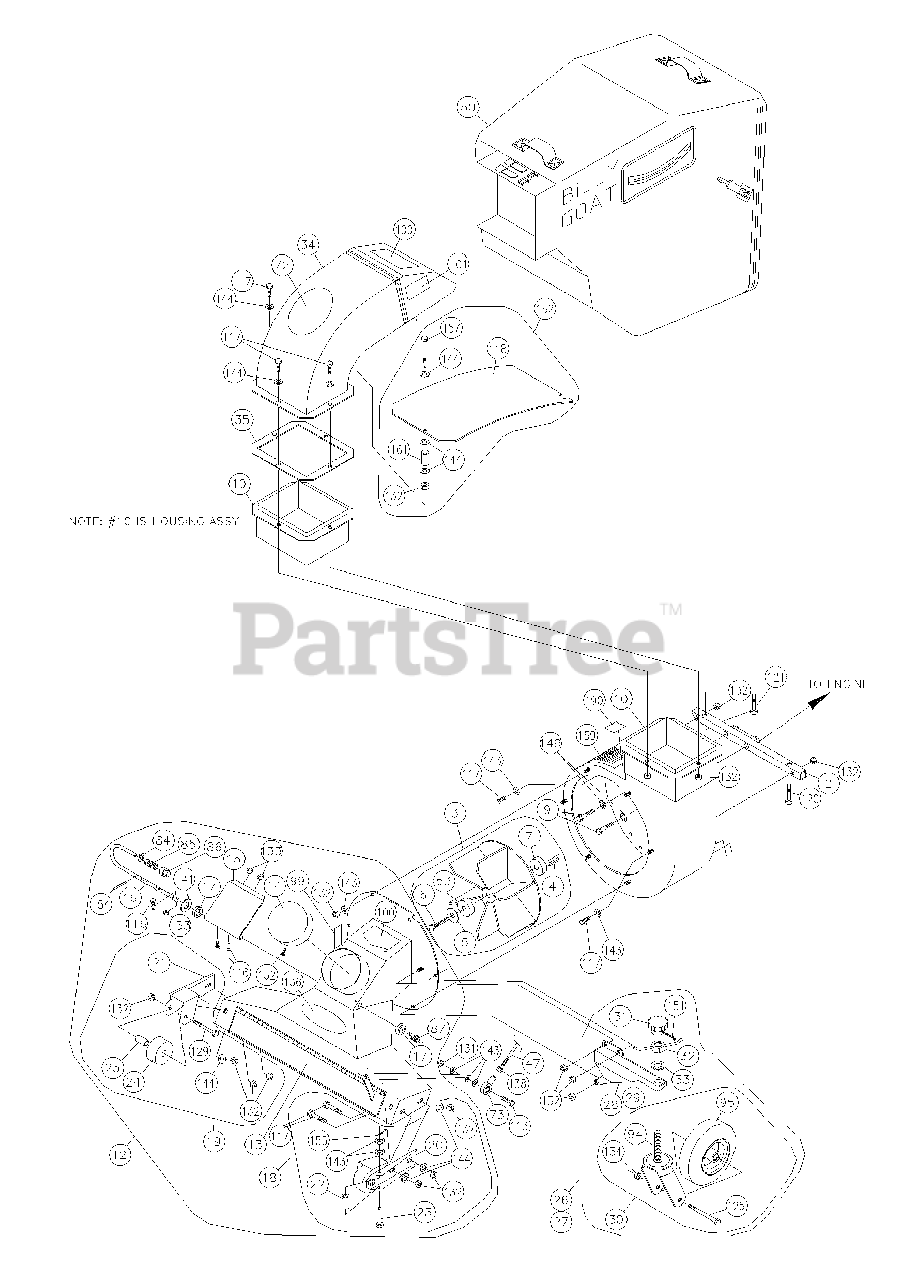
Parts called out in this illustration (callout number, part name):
1	ENGINE 9 HP HONDA
2	ANGLE MOUNT HDLE WA
3	IMPELLER ASSY VQ (INCLUDES ITEM 4,5,6,7)
4	KEY 0.25 SQ. X 2.75"
5	WASHER LOCK 7/16 S/T MED
6	SCREW CAP 7/16 NF x 2 1/4 GR8 TORQ 55-60 FT LBS (75-81 N.m)
7	SPACER ENGINE
8	WASHER LOCK 5/16 S/T MED
9	SCREW CAP 5/16 NF x 2 1/2 GRD. 8
10	HOUSING ASSEMBLY W/LABELS VQ
11	FRAME WA VQ
12	NOZZLE ASSEMBLY VQ
13	NOZZLE ASSY W/LABELS
14	HOSE TUBE PLUG VQ
15	PLATE DOOR NOZZLE HOSE
16	ROD DIVERTER VQ
17	GROMMET FLG. 1/2 MOLDED
18	BRKT BOGIE ASSY LH
19	BRKT BOGIE ASSY RH
20	BRKT BOGIE WA LH
21	BRKT BOGIE WA RH
22	ROLLER GUIDE
23	PIN ROLLER
24	WHEEL BOGIE 3"
25	SPACER 5/16 X 1 5/8
26	CASTER & BRKT LH ASSY SEMI-PNEU VQ
27	CASTER & BRKT RH ASSY SEMI-PNEUVQ
28	BRKT LH WA 8" CASTER
29	BRKT RH WA 8" CASTER
30	CASTER ASSY 8" SEMI-PNEU 3/4 NC (INCL ITEM 33 (4), 94, 95, 125, 134)
31	KNOB HAND
32	NUT WING WA
33	WASHER 3/4 NYLON
34	ELBOW ASSY W/LABELS VQ
35	GASKET FLANGE TRANSITION VQ
36	HANDLE BRACE REAR
37	HANDLE LOWER VQ
38	TUBE HANDLE BAG SUPPORT
39	ROD BAG LOOP
40	PLUG TUBE INSERT 1" OD
41	HANDLE ASSY UPPER W/GRIP (39, 45, 46, 81, 114, 115, 131, 163)
42	SWITCH & WIRE ASSY(ITEMS 107,109,110)
43	CONTROL THROTTLE ASSY VQ SERVICE
45	DOOR NOZZLE FRICTION ASSY
47	ROD DOOR NOZZLE
48	BAR LEVER DOOR
49	PLATE FRICTION LIFT
50	BAG ASSY VQ / TURF BAG 830313
51	DIFFERENTIAL ASSY
52	SPROCKET 35 TOOTH #41
53	WASHER 1.5 OD X .453 ID X .25 THK
54	WHEEL 13" x 6.5" PNEU. SP
55	BRG ASSY VQSP
56	BRKT MOUNT BEARING
57	TRANSMISSION 5 SPEED 1 REV W/BRAKE (TECUMSEH)
58	CHAIN #41 x 68P VQSP
59	BELT “V” 4L x 34" OUTSIDE LG.
60	PULLEY 5.0 DIA. A SEC 0.625 ID
61	KEY HIPRO 3/16 X 3/4
62	PULLEY IDLER
63	BOLT IDLER
64	ARM IDLER WA VQ
66	BRKT TRANSMISSION WA VQ
67	BRKT TRANSMISSION REAR WELD LONG
68	BAR LINK SHIFT OFFSET VQ
69	GUARD DIFFERENTIAL VQ WELD
70	GUARD CHAIN VQ WELD
71	GUARD PULLEY W/LABEL
72	LABEL PRODUCT DECAL LG CIRCLE
73	SPHERICAL ROD END MSF-5
74	CABLE CLUTCH ASSY
75	CONTROL SHIFT VQSP
77	CONTROL ASSY VQSP
78	BRACKET CONTROL SHIFT
79	COVER CONTROL SHIFT VQ
80	ROD BAIL CLUTCH
81	GRIP HANDLE 1" x 13"
82	BAR BRAKE CABLE MOUNT
83	WIRE BELT GUIDE VQ
84	GRIP RING
85	SPRING COMPRESSION
87	SPRING DOOR
89	LABEL DANGER GUARDS
91	KEY SQ 3/16 X 1 3/4
92	WASHER 5/16 TWISTED TOOTH
94	FORK CASTER 8" 3/4 NC
95	VQ CASTER WHEEL
97	GUARD BRAKE VQ
98	GUARD BELT VQ
99	LABEL DIVERTER INSTRUCTIONS
100	LABEL DANGER
101	LABEL DANGER FLYING MATERIAL
103	PIN CLEVIS
106	LABEL CLUTCH VQ
107	SWITCH ROCKER
109	HARNESS ENGINE KILL 33"
110	CONNECTOR TAP
111	LABEL OIL
113	SCREW CAP 1/4-20 x 1 1/4"
114	RING RETAINING "E" 3/4
115	SCREW CAP 1/4-20 x 2"
116	SCREW CAP MACH 10-18X3/4 WF ZP
117	SCREW CAP 5/16-18 x 3/4"
118	PLATE DEBRIS DEFLECTOR
119	SCREW CAP 5/16-18 x 1 1/4"
120	SCREW CAP 5/16-18 x 1 1/2
121	SCREW CAP 5/16-18 x 1 3/4"
122	SCREWCAP 5/16-18 X 2 1/4"
123	BOLT CARRIAGE 5/16-18 X 3/4
124	SCREW #10-24NC X 5/8 HEX
125	SCREW CAP 1/2-10 x 4 1/2"
126	SCREW CAP 1/4 NF x 1/2 GR. 5"
127	SCREW CAP 5/16 NF x 1 3/4"
129	SCREWCAP 5/16-18 X 2 1/4"
131	NUT LOCK 1/4 NC
132	NUT LOCK 5/16 NC
133	NUT LOCK 10-24
134	NUT LOCK 1/2"-13 LT WT TH ZP
135	NUT LOCK 3/8 NC THIN HT
136	LABEL PRODUCT DECAL VQ
137	NUT REG. 3/8 NC
138	NUT REG. 5/16 NF
139	WASHER SAE 1/4
140	WASHER SAE 5/16
141	WASHER SAE 3/8
144	WASHER FLAT CUT 5/16
146	WASHER 3/4 (0.765 x 1.25 x 0.06)
147	BOLT SHOULDER 3/8 X 3/4"
148	WASHER LOCK 1/4
149	WASHER LOCK 5/16
150	LABEL SPEED CONTROL
151	SCREW MACH #10-24 x 2"
152	SCREW SHT. MTL 1/4 AB x 3/4
153	SCREW SELF-TAP 5/16 NC x 3/4 HEX
154	PIN ROLL 1/8 x 3/4
155	PIN COTTER 3/32 x 3/4
156	PIN COTTER 1/8 x 1"
157	SCREW CAP 5/16-18 x 2 3/4
158	LOOSE PARTS BAG ASSY VQ
159	LABEL DANGER INSTRUCTIONS
162	DEFLECTOR DEBRIS ASSY
163	SCREW CAP 1/4-20 x 2"
164	PLATE QUAD LIFT
165	PLATE CLAMP LIFT
166	BALL 1/4"
167	SCREW CAP 1/4-20 x 1"
168	SCREWCAP 5/16-18 X 2 1/2"
169	NUT LOCK #10-24 NC LT
172	WASHER - BELVILLE 1/4"
173	NUT LOCK 1/4-20
174	NUT JAM 1/4" NC HEX
175	WASHER LOCK - EXT 1/4
178	EYEBOLT PIGTAIL 5/16-18 X 1 1/4"
179	WASHER SHIM 0.020"
180	CAP ROPE GUIDE BOLT VQ
182	SNAP RING
190	LABEL SPARK ARRESTOR EN/SP
200	NUT 5/116" - 18 HEX ZP
205	LABEL MADE IN U.S.A.
